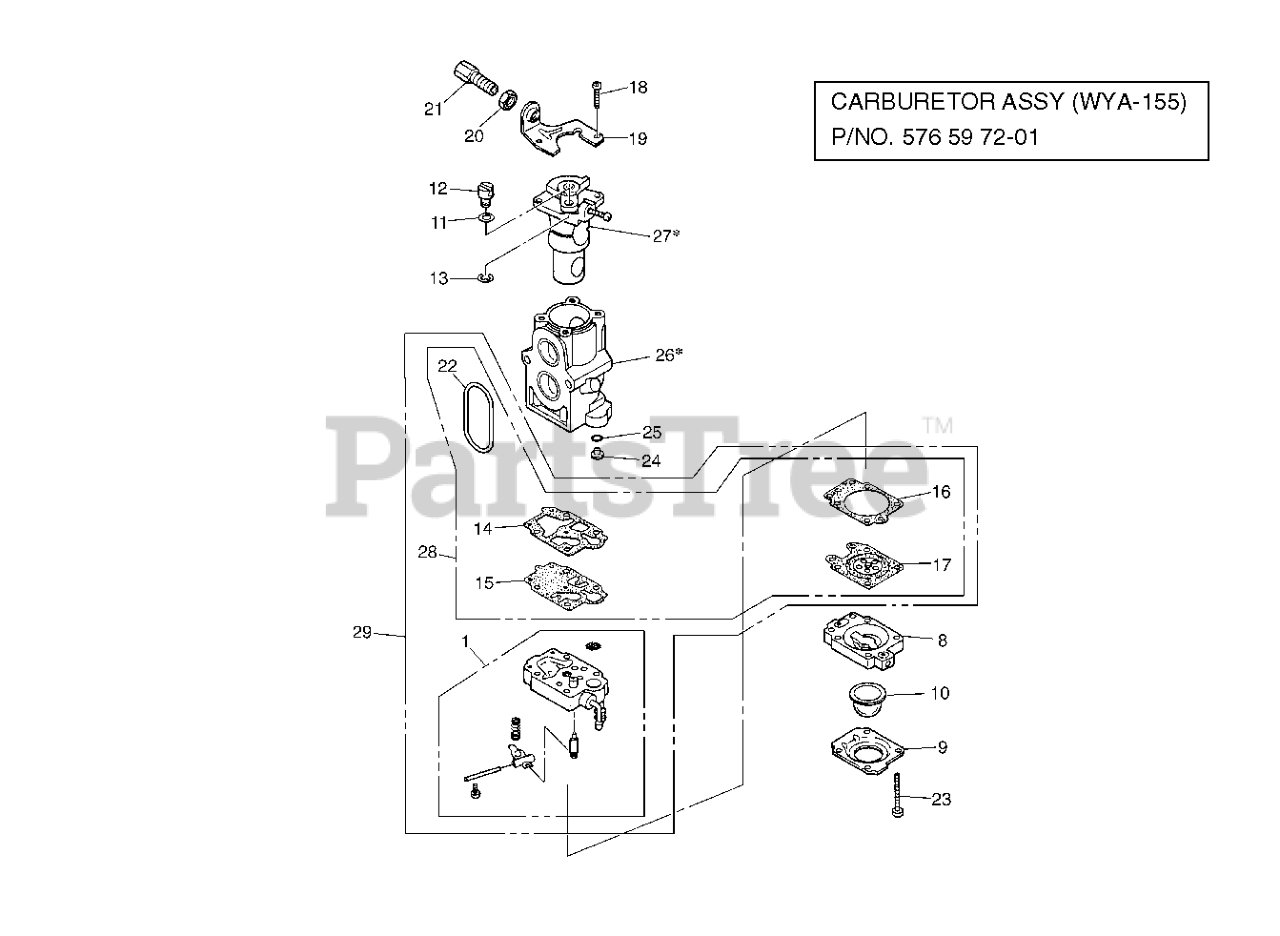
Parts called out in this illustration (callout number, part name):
1	BODY-A-PUMP
9	1OVER
11	WASHER
12	SWIVEL
13	RING
15	DIAPHRAGM
17	DIAPHRAGM
18	SCREW
19	BRACKET
20	NUT
21	ADJUSTER
22	RING
24	JET #61
26	CARBURETOR
27	CARBURETOR
28	GASKET KIT
29	REBUILD KIT
